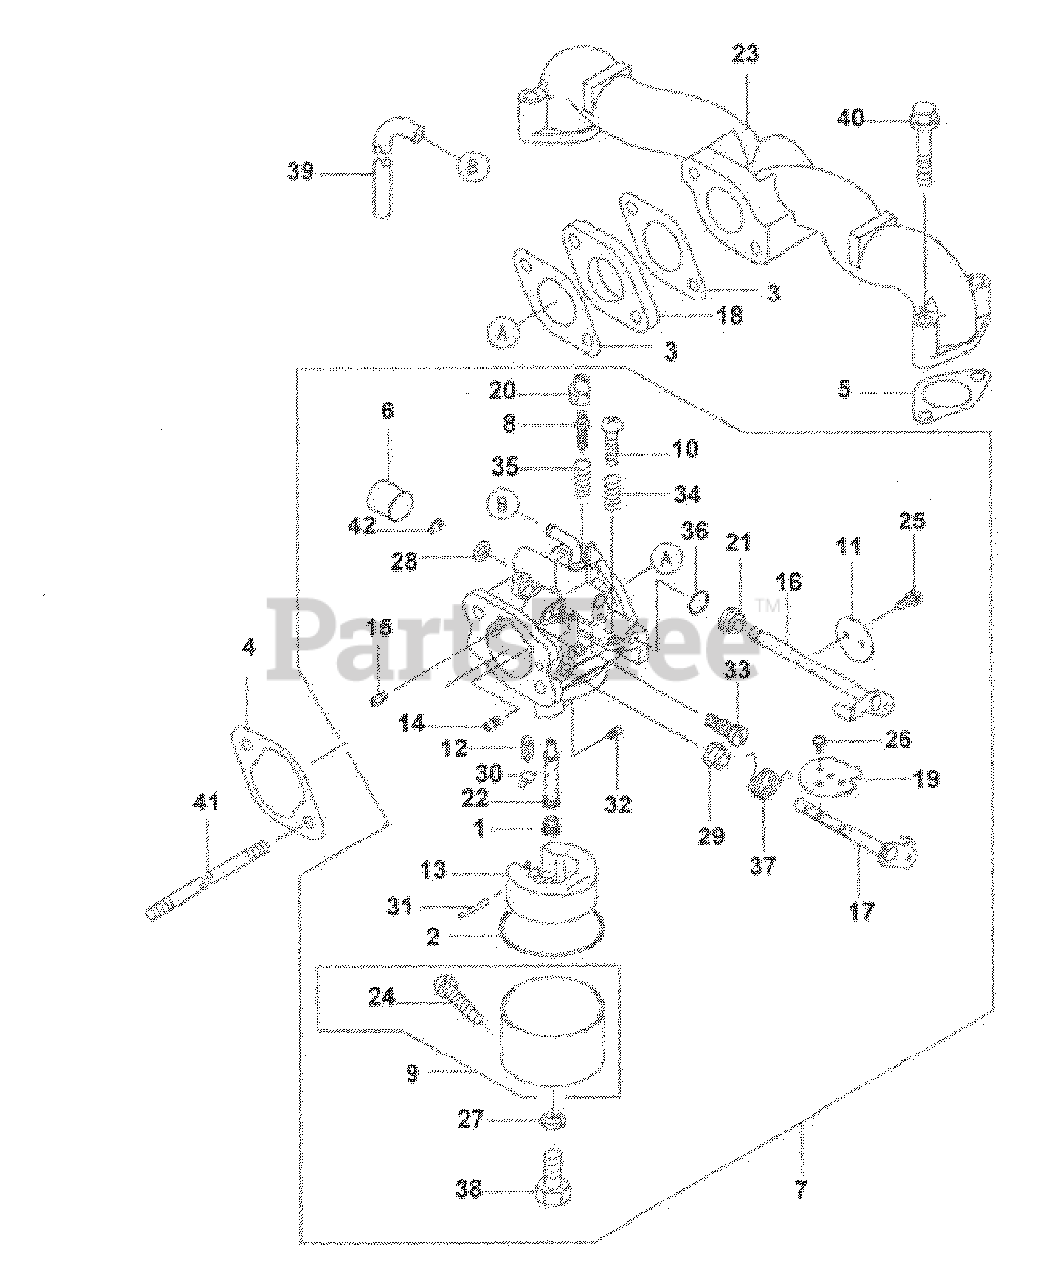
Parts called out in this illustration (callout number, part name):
3	Insulator Gasket
4	Air Cleaner Gasket
5	Manifold Gasket
7	Carburetor Assy.
8	Pilot Air Screw
10	Throttle Stop Screw
11	Throttle Valve # 130
14	Air Jet, # 1.7
15	Air Jet, # 1.2
16	Throttle Shaft
18	Insulator
22	Main Nozzle, #113A
23	Intake Manifold
32	Main Jet # 125
33	Pilot Jet, # 48.8
40	Flange Bolt
42	E-Style Circlip
